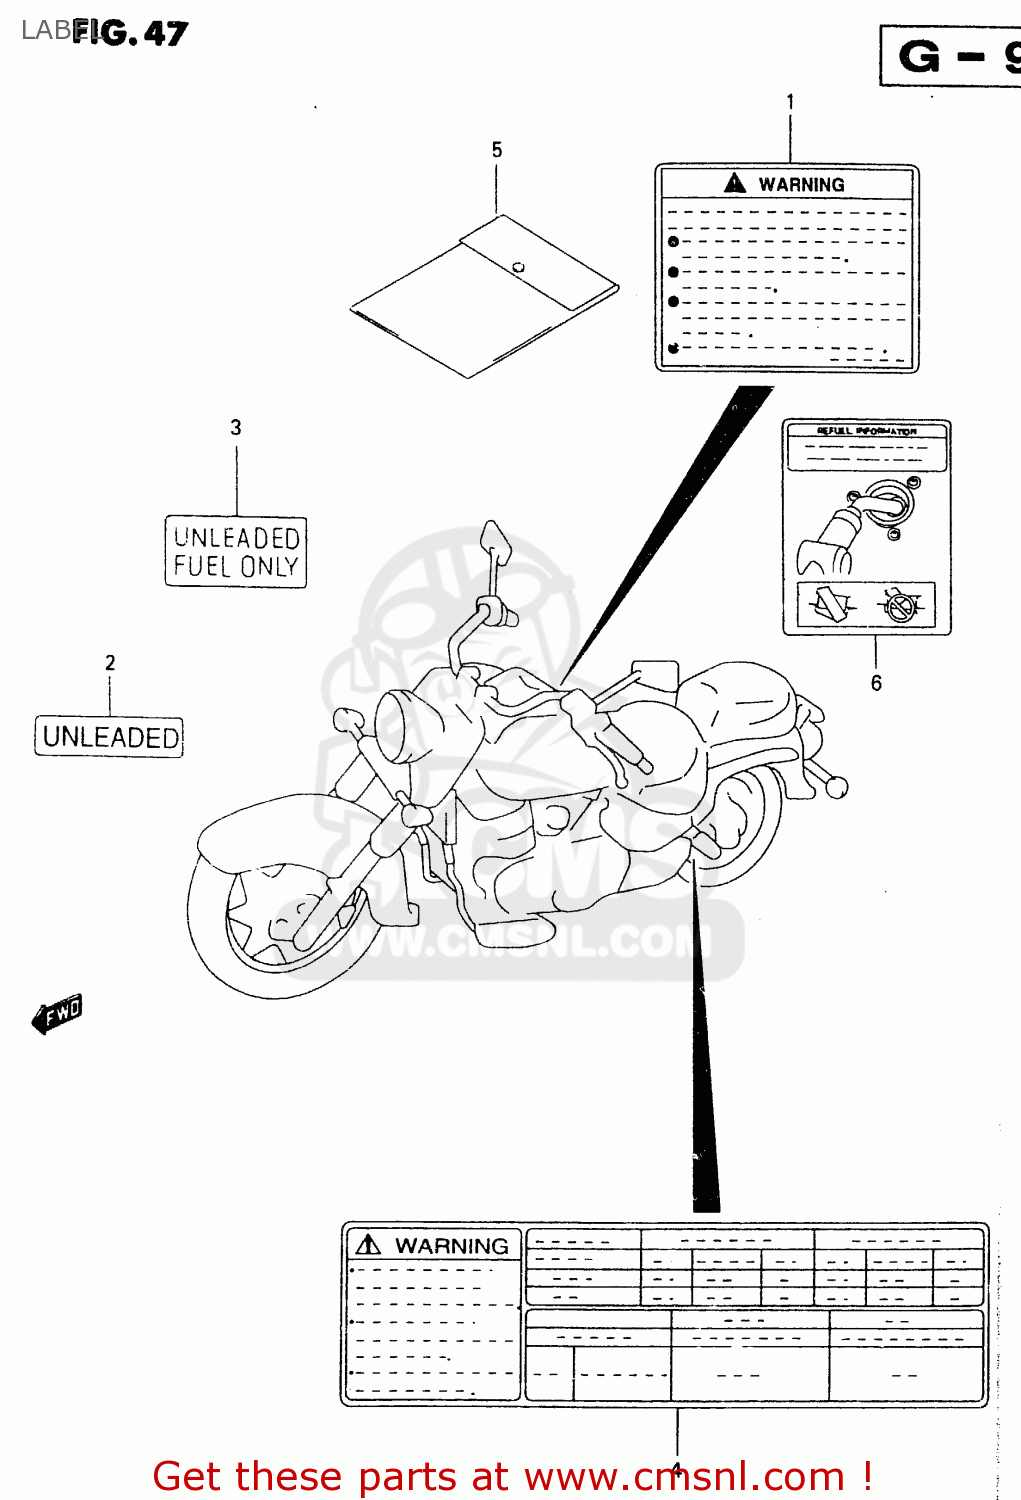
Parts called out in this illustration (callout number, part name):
1	LABEL,WARNING
2	LABEL,CAUTION
3	LABEL,FUEL CAUTION
4	LABEL, TIRE INFORMATION
5	BAG COMP,OWNERS MANUAL
6	LABEL,FUEL INFORMATION
